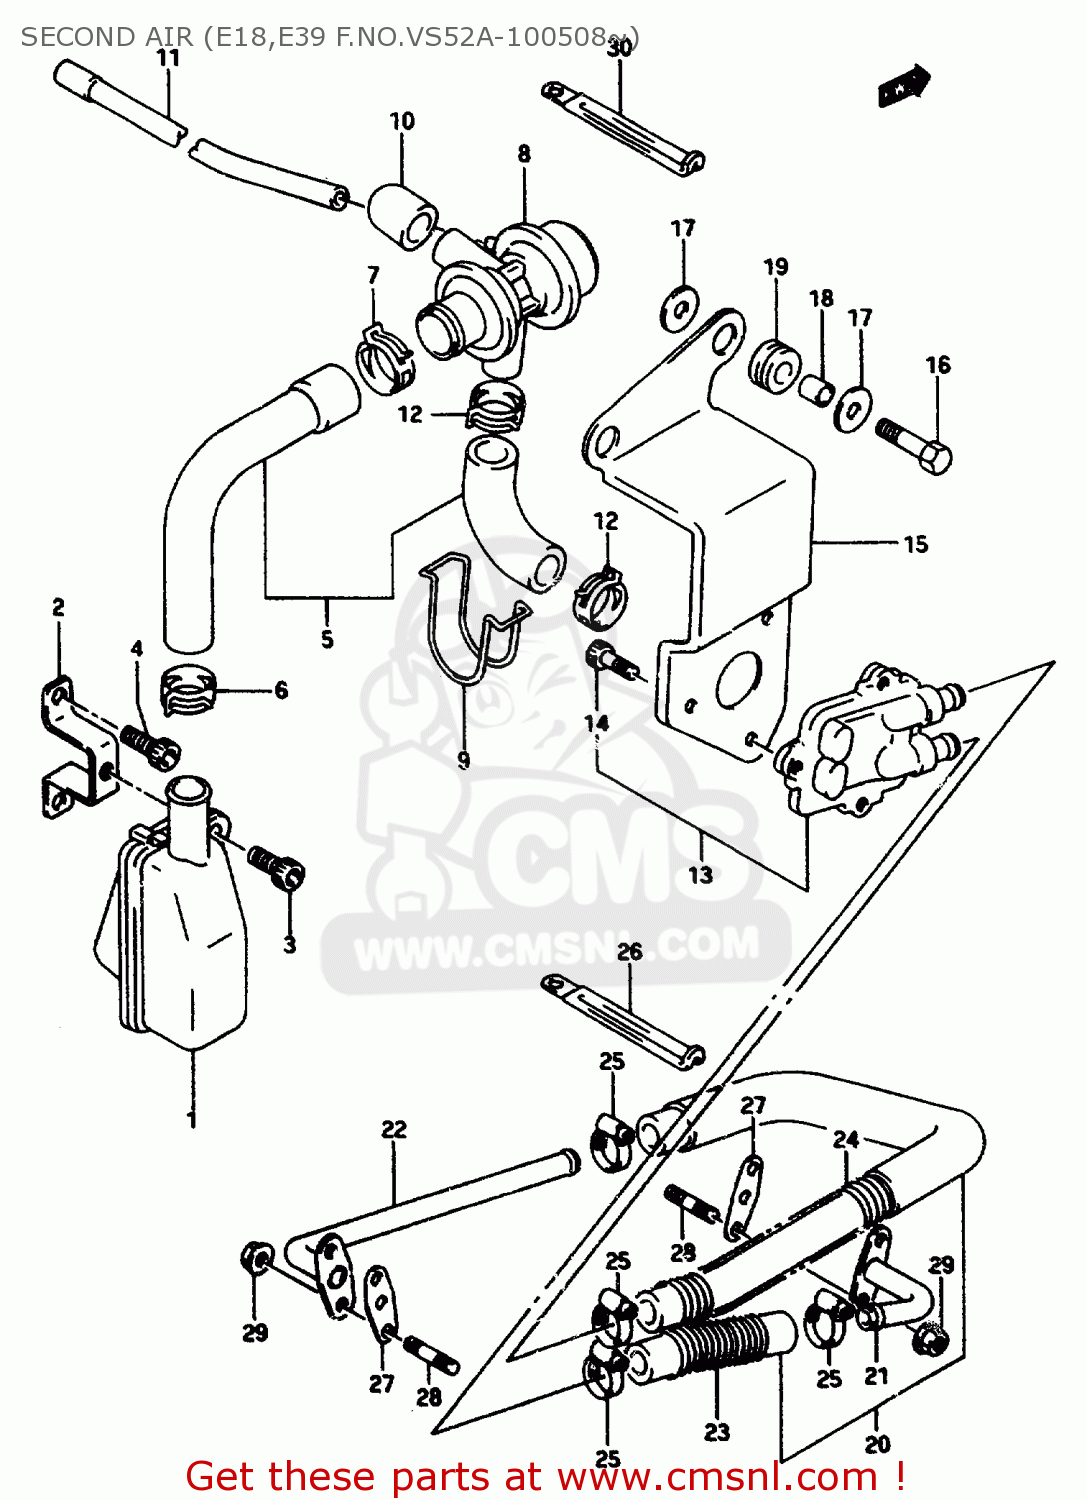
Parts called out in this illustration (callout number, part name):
1	CLEANER ASSY,AIR NO.2
2	BRACKET,2ND AIR CLEANER
3	BOLT
4	BOLT
5	HOSE SET,2ND AIR NO.2
6	CLIP
7	CLIP
8	VALVE ASSY,AIR SWITCHING
9	CLAMP,SWITCHING VALVE
10	CAP,SWITCHING VALVE
11	HOSE(4.5X8.5X600)
12	CLIP
13	VALVE ASSY,2ND AIR REED
14	BOLT
15	BRACKET, 2ND AIR VALVE
16	BOLT
17	WASHER(6.5X20X1.6)
18	SPACER(6.5X10X10)
19	CUSHION
20	HOSE SET, 2ND AIR
21	PIPE,2ND AIR FR
22	PIPE,2ND AIR RR
23	SPRING, FRONT HOSE
24	SPRING, REAR HOSE
25	CLAMP
26	CLAMP(L:80)
27	GASKET,SECOND AIR PIPE (N (NAS)
28	STUD 6X16
29	NUT
30	CLAMP(L:80)
